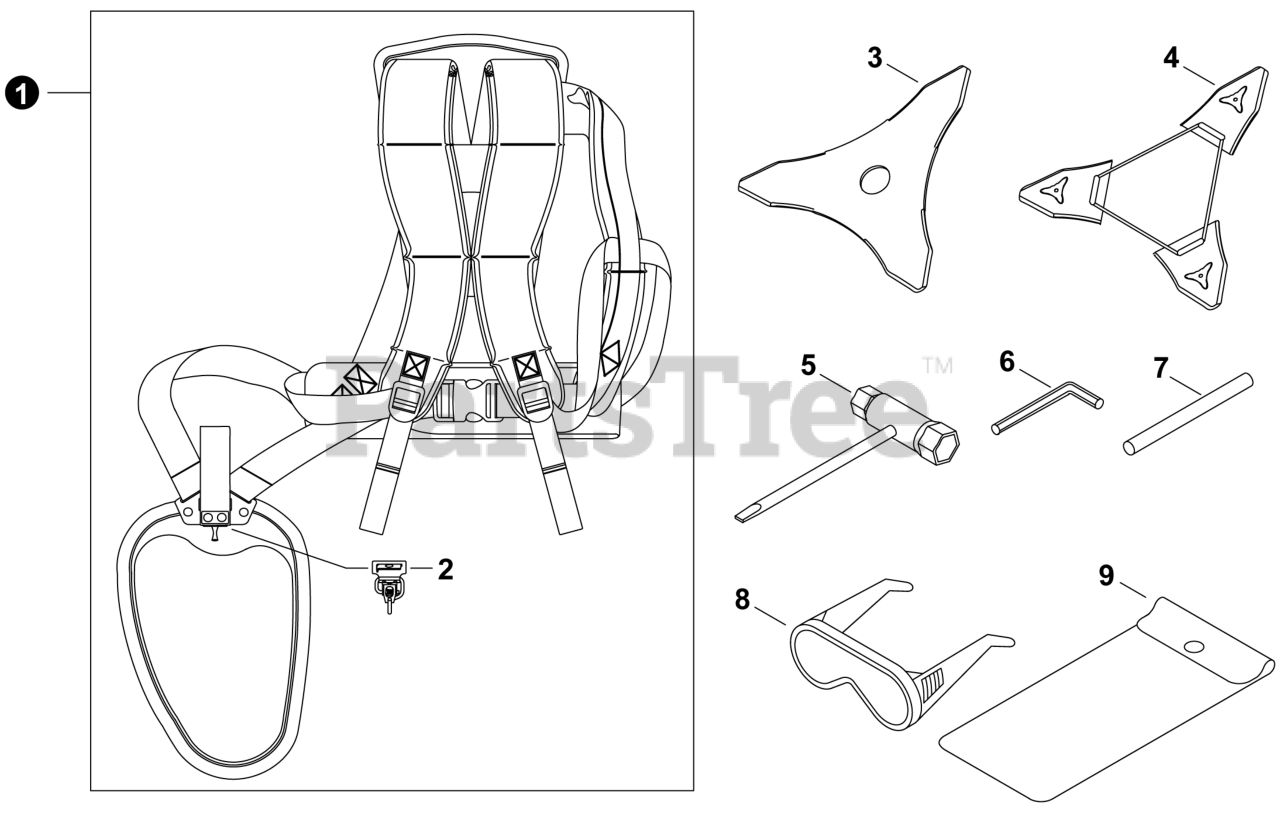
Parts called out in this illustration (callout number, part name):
1	HARNESS ASSY
2	HOOK, SNAP
3	BLADE, 10" 3-TOOTH
4	SCABBARD
5	T-WRENCH 17×19 L200
6	WRENCH, ALLEN
7	TOOL, LOCKING 5×120 MM
8	GLASSES, SAFETY
9	BAG, TOOL
